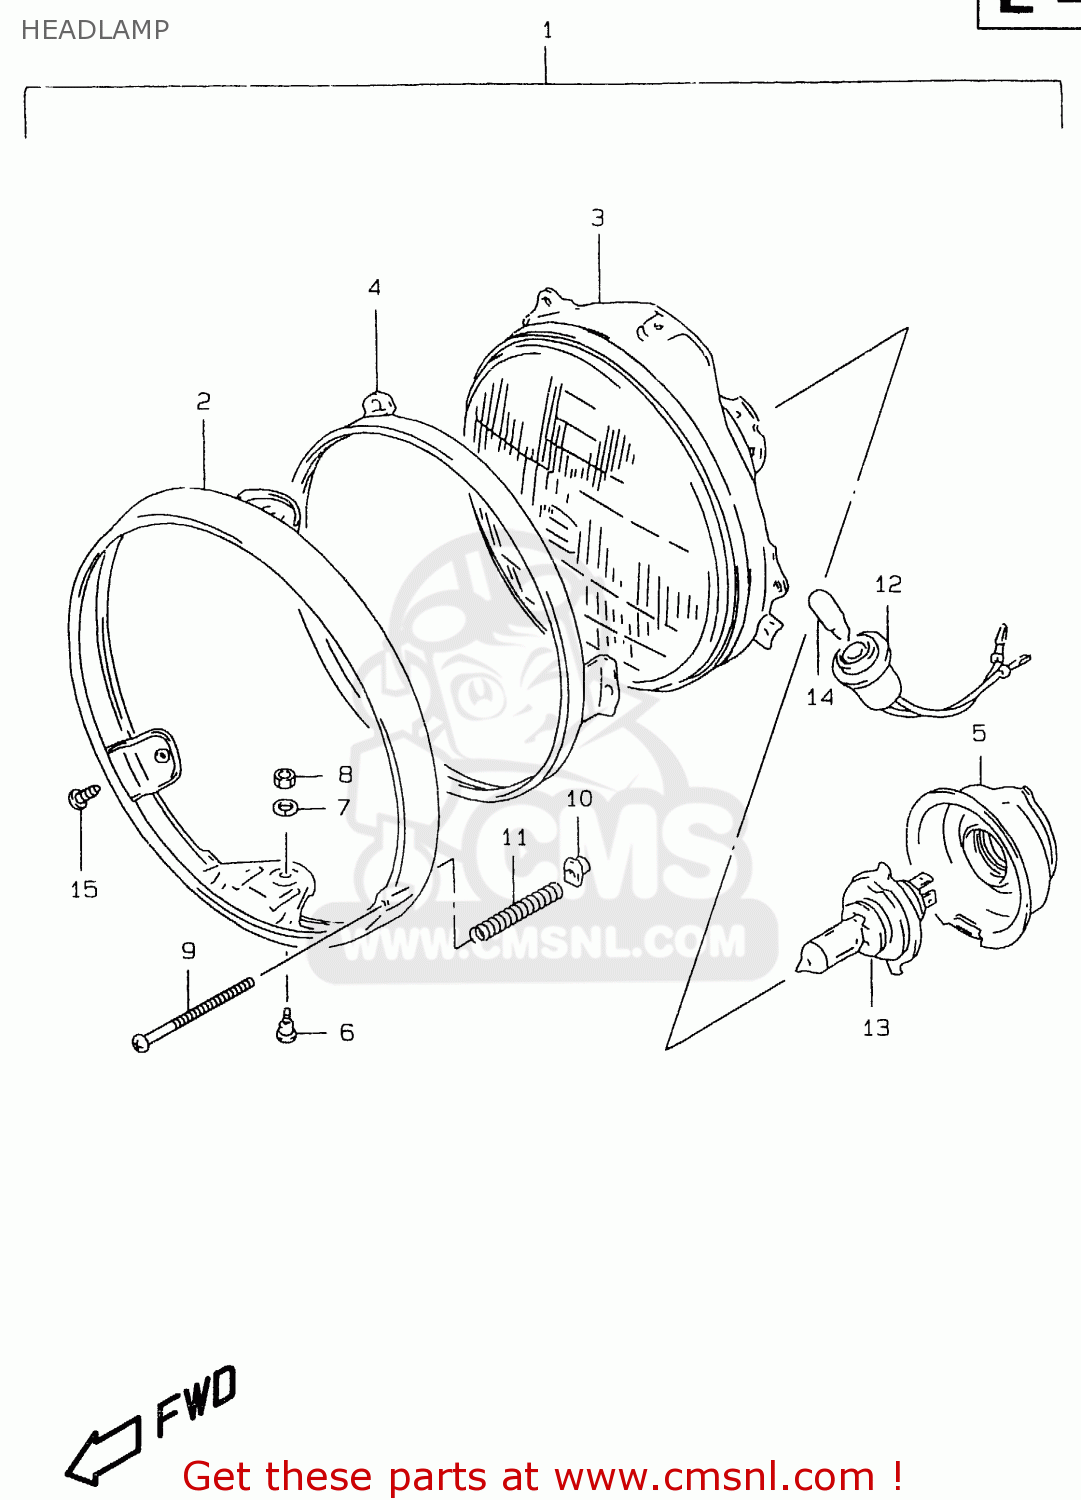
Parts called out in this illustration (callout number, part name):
1	HEADLAMP ASSY
2	RIM,HEADLAMP
3	LAMP UNIT
4	RING
5	COVER,SOCKET
6	H/LAMP LENS UNIT FITING SCRE
7	WASHER,LOCK
8	NUT
9	SCREW
10	NUT
11	SPRING,ADJUSTING
12	SOCKET
13	BULB(12V60/55W,H4)
14	BULB(12V4W)
15	SCREW
